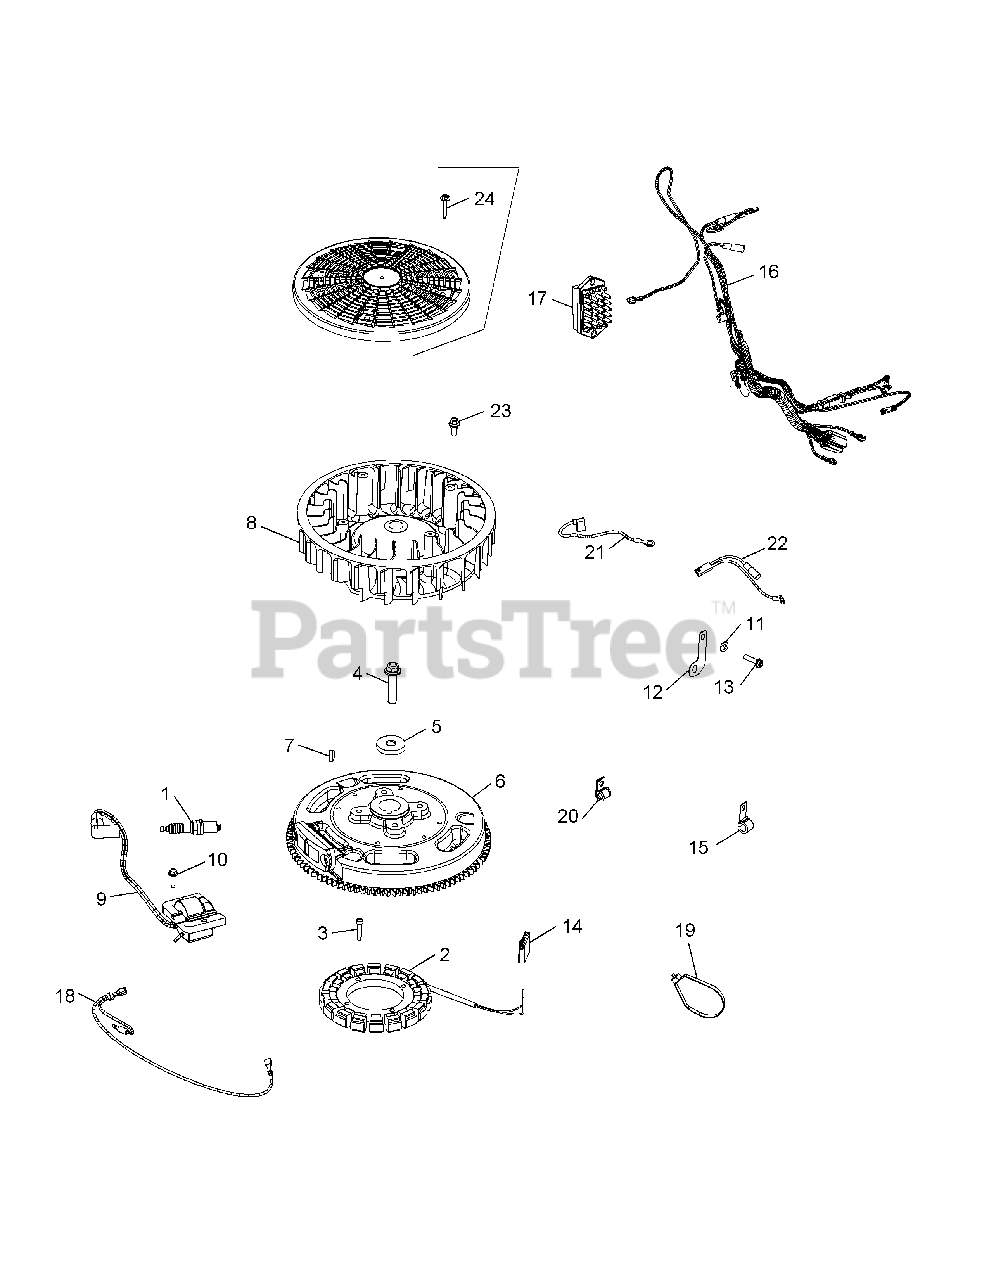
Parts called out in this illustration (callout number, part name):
2	15 Amp Stator Kit
3	Thread Forming Screw
4	Flange Screw, M10 x 1.5 x 45
5	Flat Washer, 13/32"
7	Key, 3/16 x 5/8
9	Ignition Module Kit
10	Thread Forming Screw
11	Flat Washer, 1/4
12	Ground Strap Bracket
13	Hi-Lo Hex Flange Screw
15	Cable Clip
16	Wiring Harness
17	Rectifier Regulator
23	Shoulder Bolt
24	Flange Screw, M4 x .7 x 25
